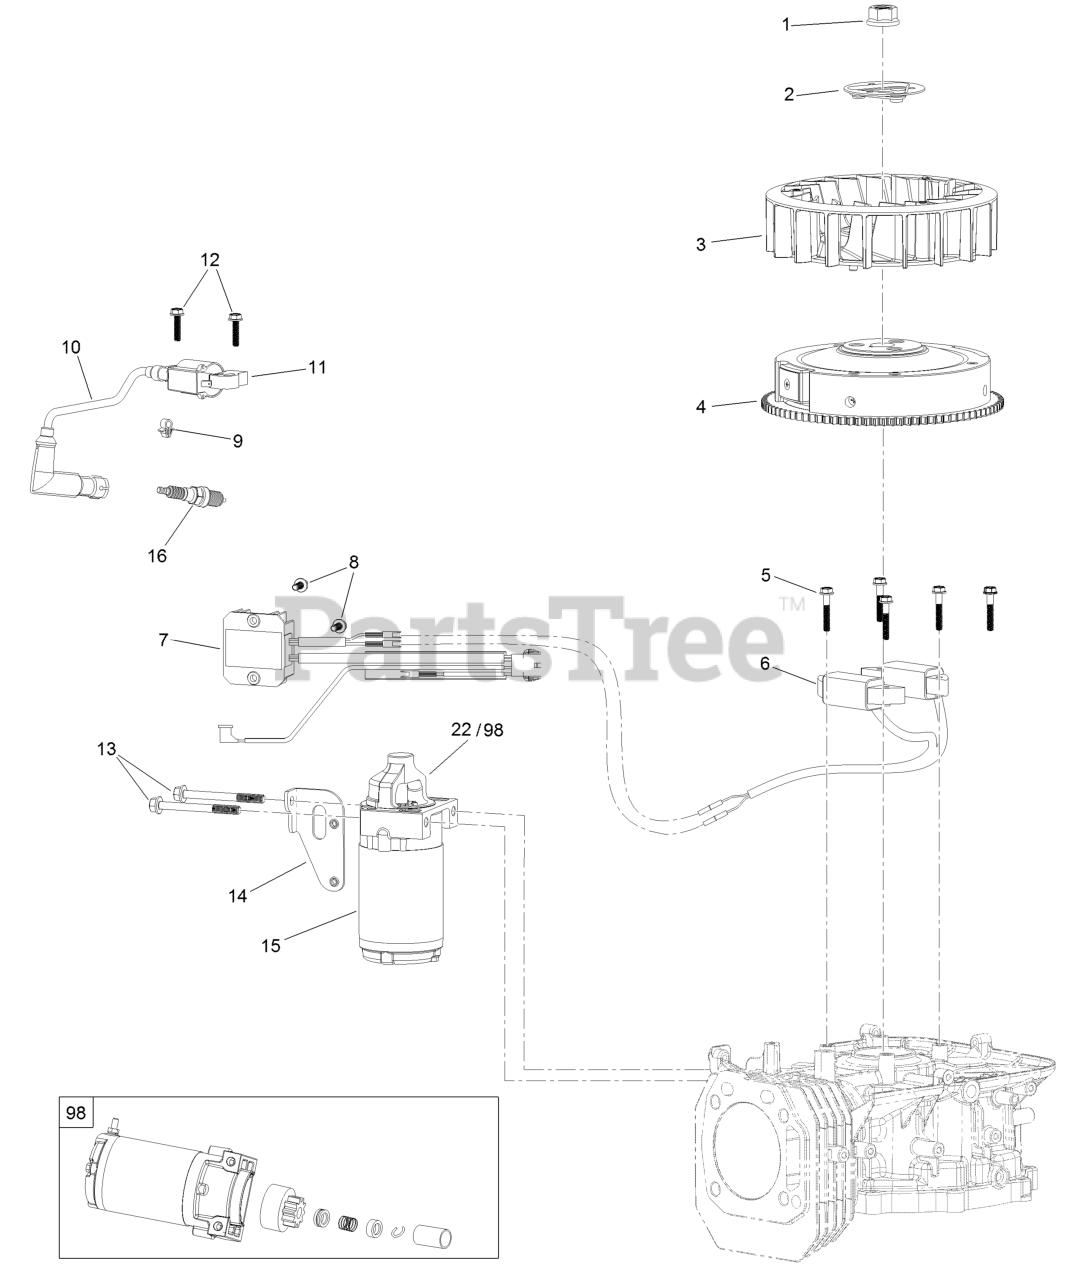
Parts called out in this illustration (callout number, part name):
1	NUT-FLANGE
2	PULLEY-STARTER
3	FAN-COOLING
4	FLYWHEEL
5	SCREW-HHF
8	SCREW-HHF
9	CLAMP-WIRE
10	BOOT-PLUG, SPARK
12	SCREW-HHF
13	SCREW-HHF
14	BRACKET-STARTER
16	Plug-Spark
98	STARTER REPAIR KIT
